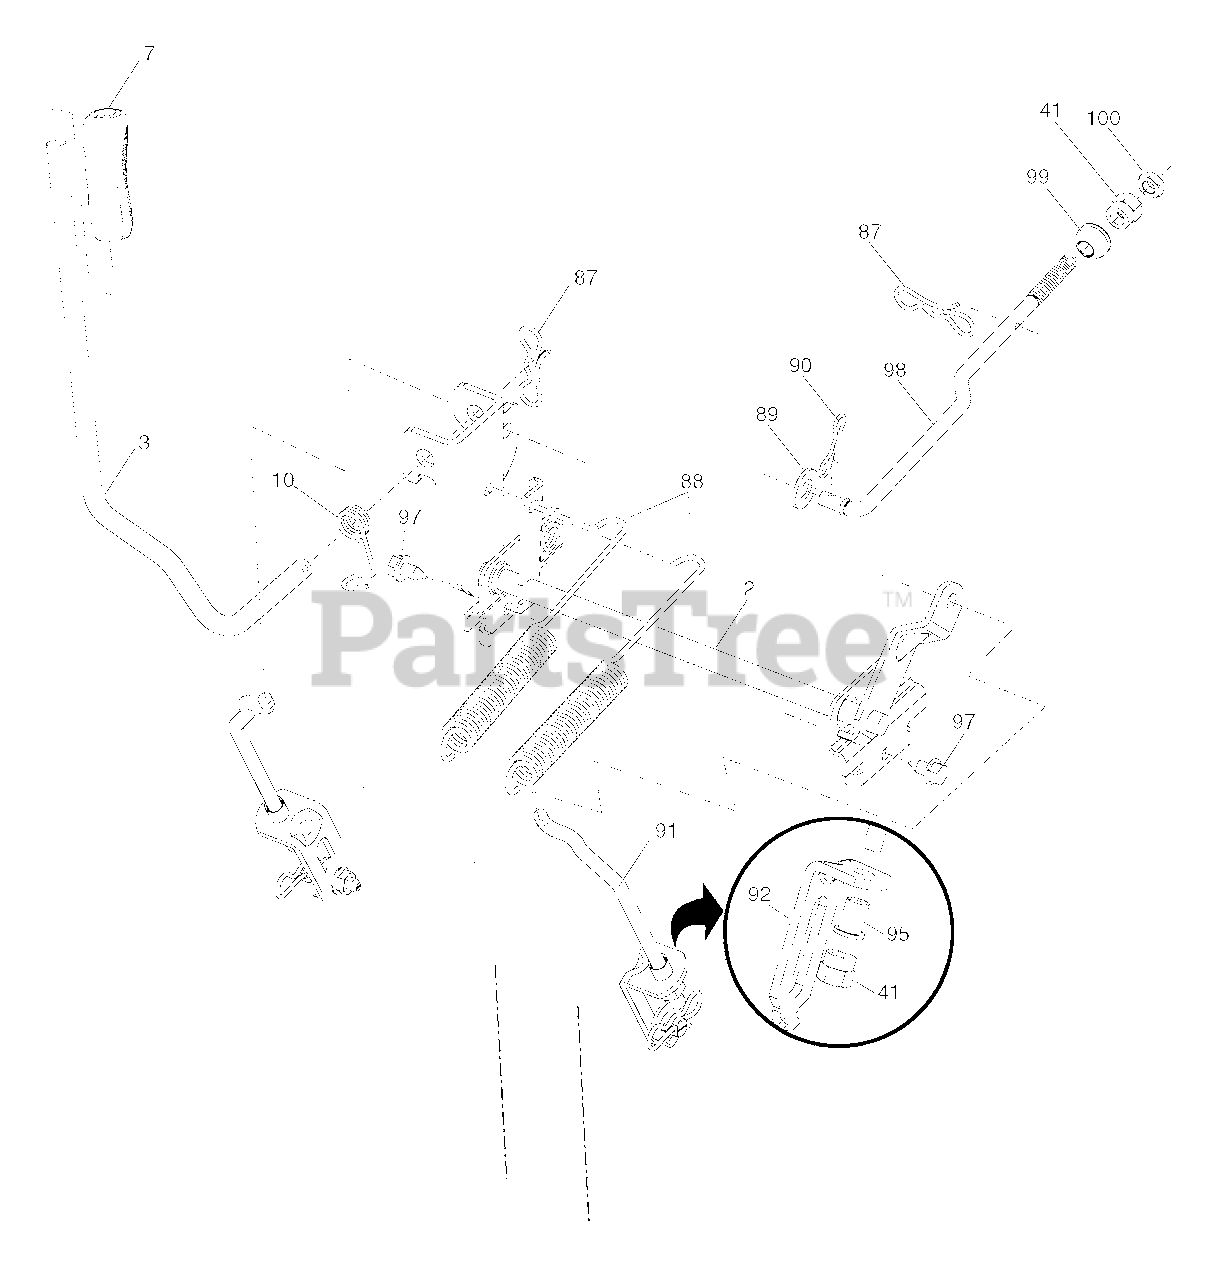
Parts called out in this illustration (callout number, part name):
2	Shaft Asm., Lift
3	Lever Asm., Lift Rh
7	Grip, Lever
10	Spring Torsion
41	Nut, 7/16-20
87	Pin Cotter 7/16 Bow Tie Lock
88	Spring Lift Assist
89	Washer Clear Zinc
90	Pin Cotter 5/16 Bow Tie Lock
91	Link Lift Susp Mower Rear
92	Bracket Connect Link Lift
95	Bushing Alignment Link Lift
97	Screw 3/8-16 x .75 Smgml Tap/R.Z
98	Link Lift Susp. Front Mower
99	Bushing Spherical Susp Front
100	Nut Hex Jam ASF 7/16-20 unf
